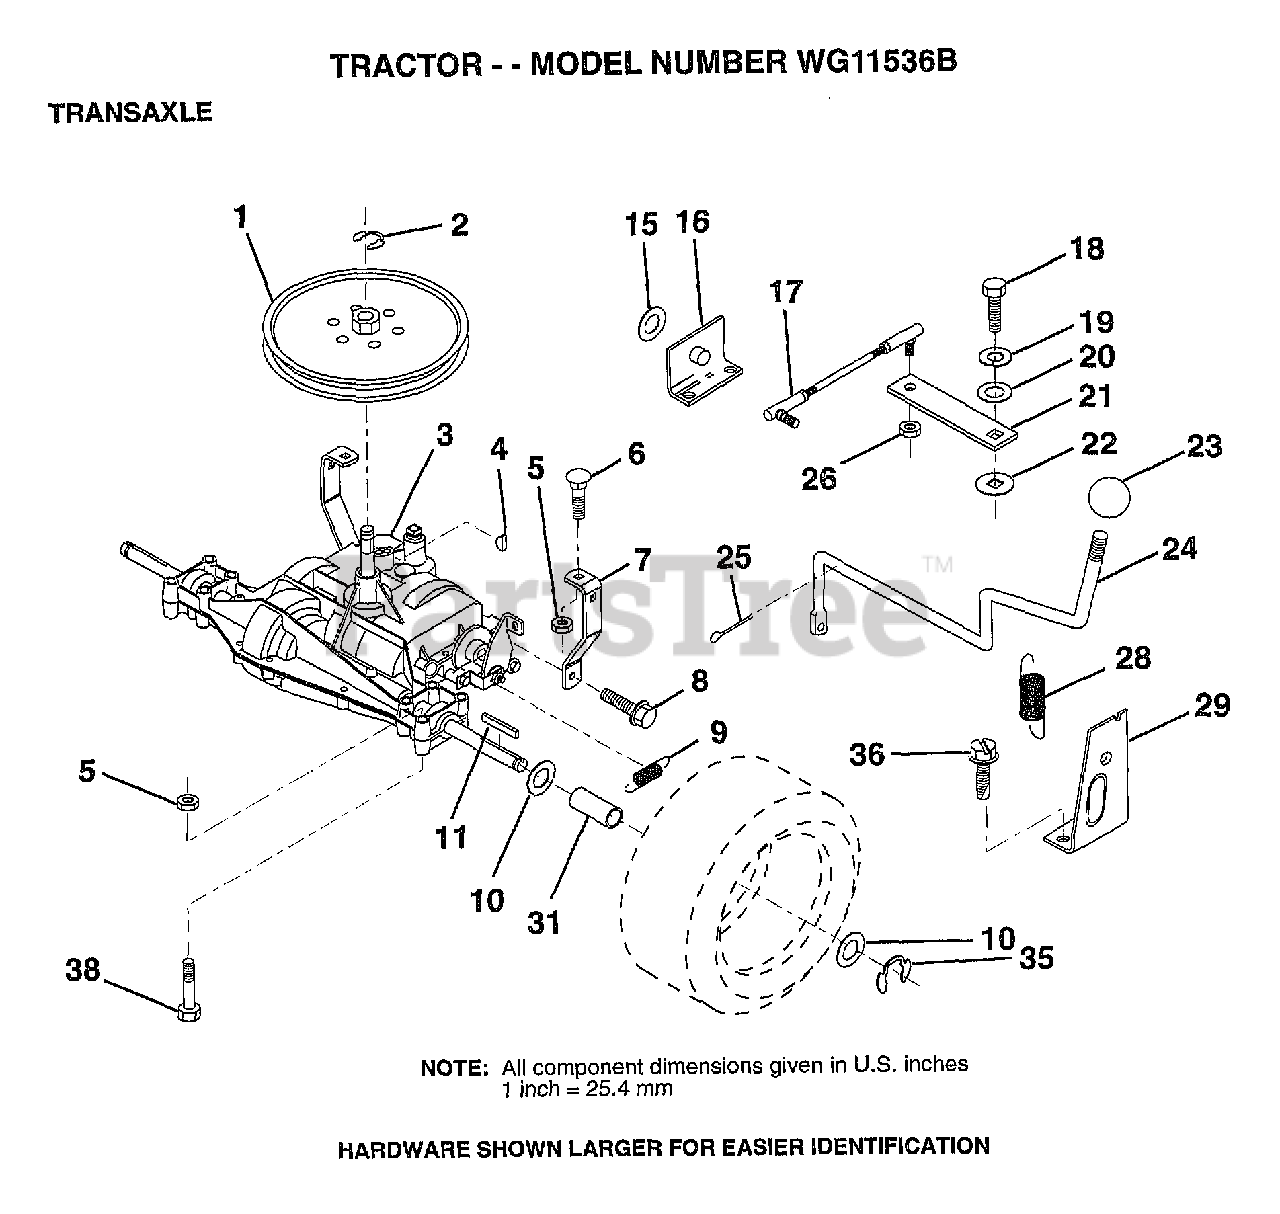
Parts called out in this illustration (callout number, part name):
1	PULLEY
6	BOLT
7	"STRAP,TORQUE"
8	SCREW
9	SPRING.BRAKE.RETU
11	SQUARE KEY
16	SUPPORT HANDLE SHIFT LH
17	LINK SHIFT
18	BOLT.1/4-28.W/PAT
19	LOCKWASHER
20	WASHER LT
22	WASH-SHFT PLT LT
23	KNOB T (1/2-HOLE)
24	"ROD,SHIFT"
25	PIN COTTER 1/8
26	NUT.LOCK.5/16-24
28	"SPRING,EXT"
29	"SUPT,HDLE RH"
31	SPACER AXLE
35	E-RING LT
36	SCREW
38	BOLT.HEX.FLGHD
